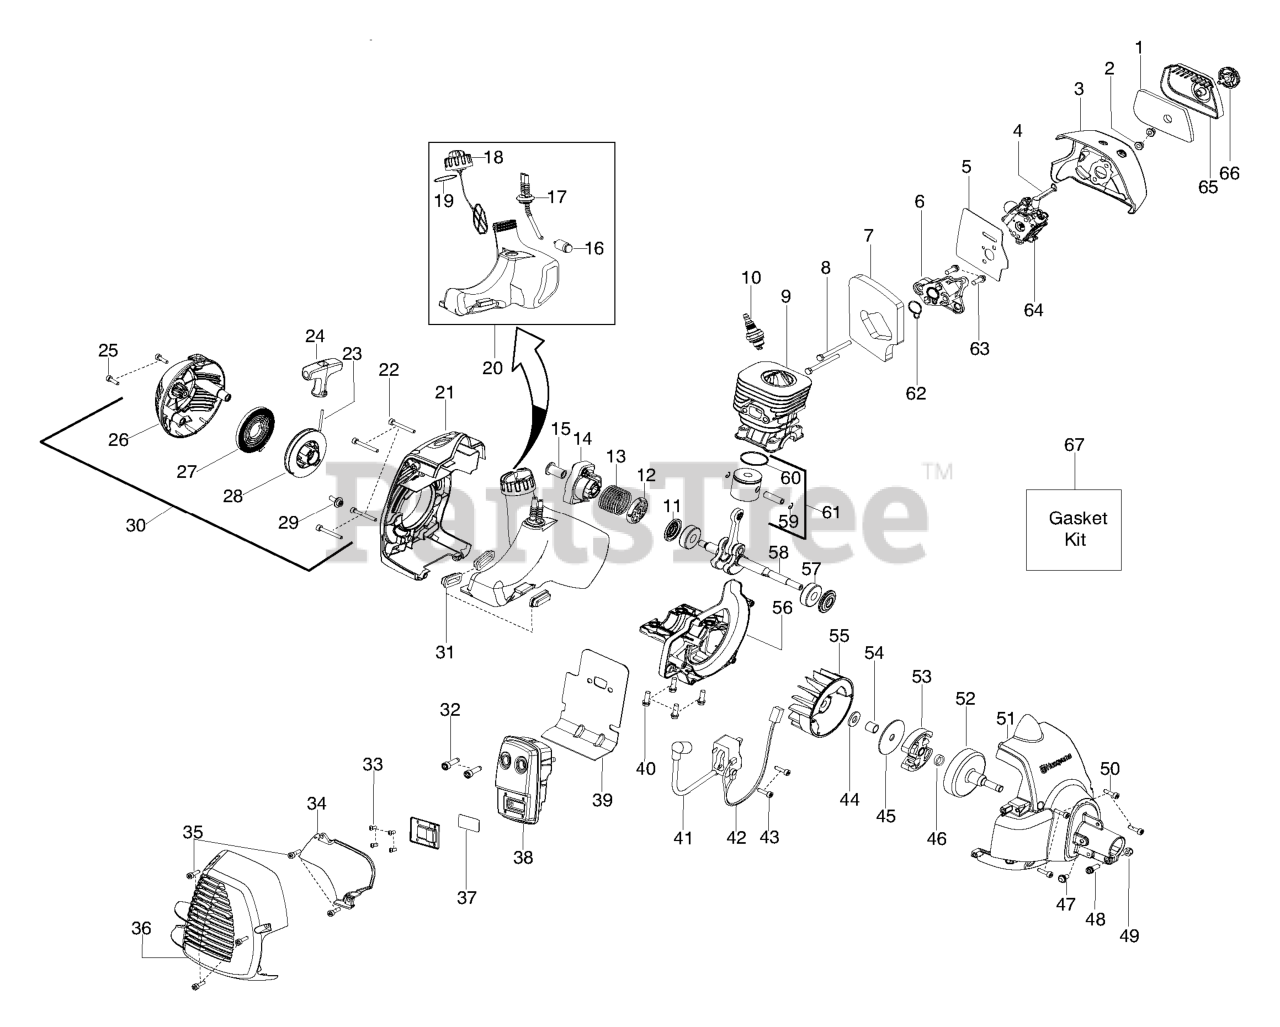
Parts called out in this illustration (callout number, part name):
2	Nut-Carb. Screw
3	Air Box
4	Kit-Choke Lever
5	Kit-Carb. Gasket
6	Adaptor-Carb.
7	Kit-Gasket (foam)
9	Cylinder
10	Plug-Spark (RCJ-6Y)
11	Kit-Crankshaft seal
12	Washer-Starter
13	Spring-Starter Cup
14	Assy-Starter Cup
15	Coupling-Starter
16	Assy-Fuel Filter
17	Kit-Fuel Line
18	Assy-Cap w/ret.
19	O-ring - Fuel Cap
20	Assy-Fuel Tank
21	Shroud-Rear
24	Handle-Starter
26	Starter Hsg. w/eyelet
27	Kit-Starter Spring
28	Kit-Starter Pulley
30	Assy-Starter Hsg.
31	Isolator-Tank
32	Bolt-Muffler
34	Shield-Heat
36	Guard-Muffler
37	Kit-Spark Arrestor
38	Assy-Muffler
39	Gasket-Paper Metal
41	Module
42	Assy-Leadwire
45	Washer-Clutch
46	Spacer-Clutch
51	Assy-Fan Housing
52	Assy-Clutch Drum
53	Assy-Clutch
56	Crankcase-Machined
58	Kit-Crankshaft
59	Retainer-Piston Pin
60	Ring-Piston
61	Kit-Piston
62	Kit-Gasket (adaptor seal)
64	Kit-Carb.
65	Cover-Air Box
67	Kit-Gasket
